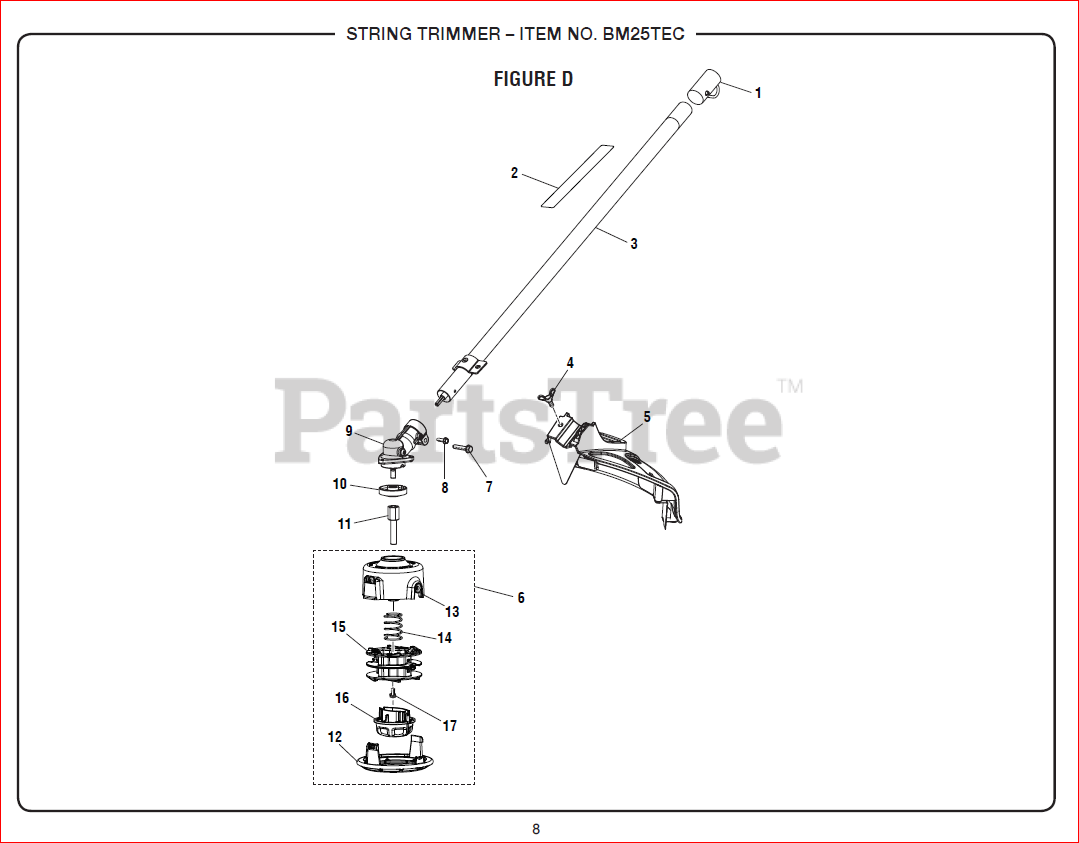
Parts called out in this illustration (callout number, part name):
1	Storage Hanger Cap
2	Warning Icon Label
3	Straight Shaft Assembly
4	Screw (#1/4-20 x 1-1/4 in. Hex Washer Hd.)
5	Grass Deflector Assembly
6	Trimmer Head Assembly (.095)
7	Screw (1/4-20 x 1-1/4 in., Hex Washer Hd. S.T.)
8	Screw w/Washer (10-24 x 5/8 in., Hex Hd. T.F.)
9	Gear Case Assembly
10	FLANGED WASHER
11	Trimmer Head Shaft Adaptor
12	Lower String Head Housing
13	Main Stringhead Housing
14	Compression Spring
15	Spool w/ Line (.095)
16	Bump Knob
17	Screw (5/16 x 1/2 in., Left Hand)
